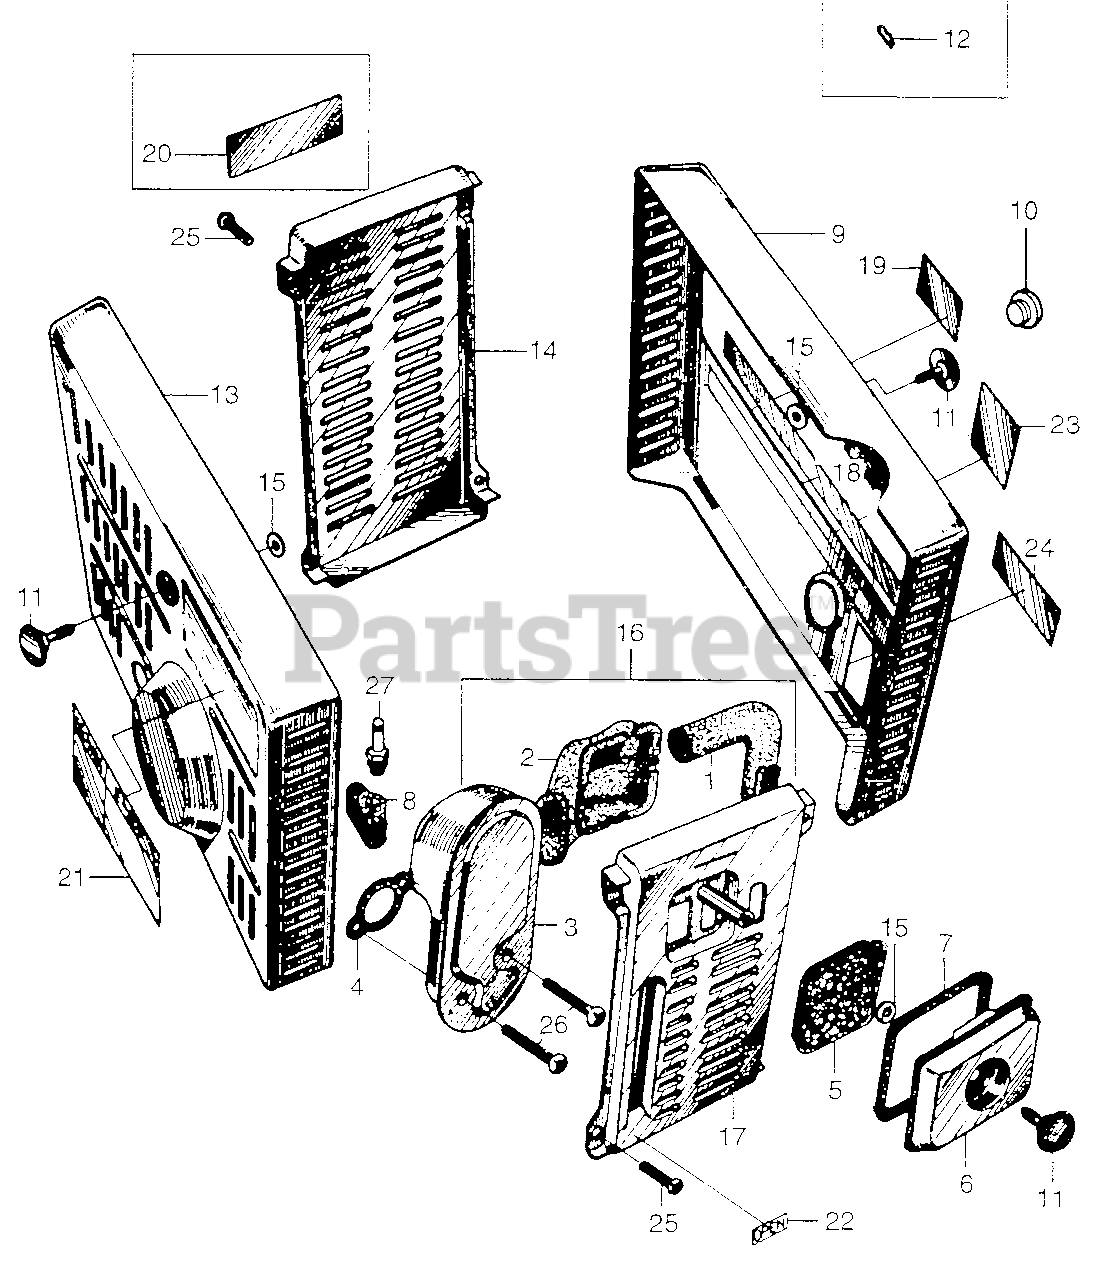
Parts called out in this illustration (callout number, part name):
1	TUBE, AIR CLEANER
1	TUBE, AIR CLEANER (NOT AVAILABLE)
2	TUBE, IN. MUFFLER CONNECTING
3	MUFFLER, IN. (NOT AVAILABLE)
4	GASKET, IN. MUFFLER (NOT AVAILABLE)
5	ELEMENT, AIR CLEANER
6	COVER, AIR CLEANER *NH2M* (METALLIC SILVER) (NOT AVAILABLE)
7	RUBBER, AIR CLEANER SEAL (NOT AVAILABLE)
8	HOLDER, SPARE PLUG
9	COVER, FR. *R15L* (WINE RED)
11	LATCH, COVER (NOT AVAILABLE)
12	PIN, LATCH SNAP
13	COVER, RR. *R15L* (WINE RED)
14	COVER, R. SIDE *NH2M* (METALLIC SILVER)
15	STOPPER, LATCH (NOT AVAILABLE)
16	COVER ASSY., L. SIDE *NH2M* (METALLIC SILVER)
17	COVER, L. SIDE *NH2M* (METALLIC SILVER)
21	PLATE, CAUTION
22	MARK, CARBURETOR
23	MARK A, OIL CHECK
24	MARK B, OIL CHECK
25	SCREW, PAN (5X10)
26	SCREW, PAN (5X20)
27	SPARK PLUG (CM6) (NGK)
